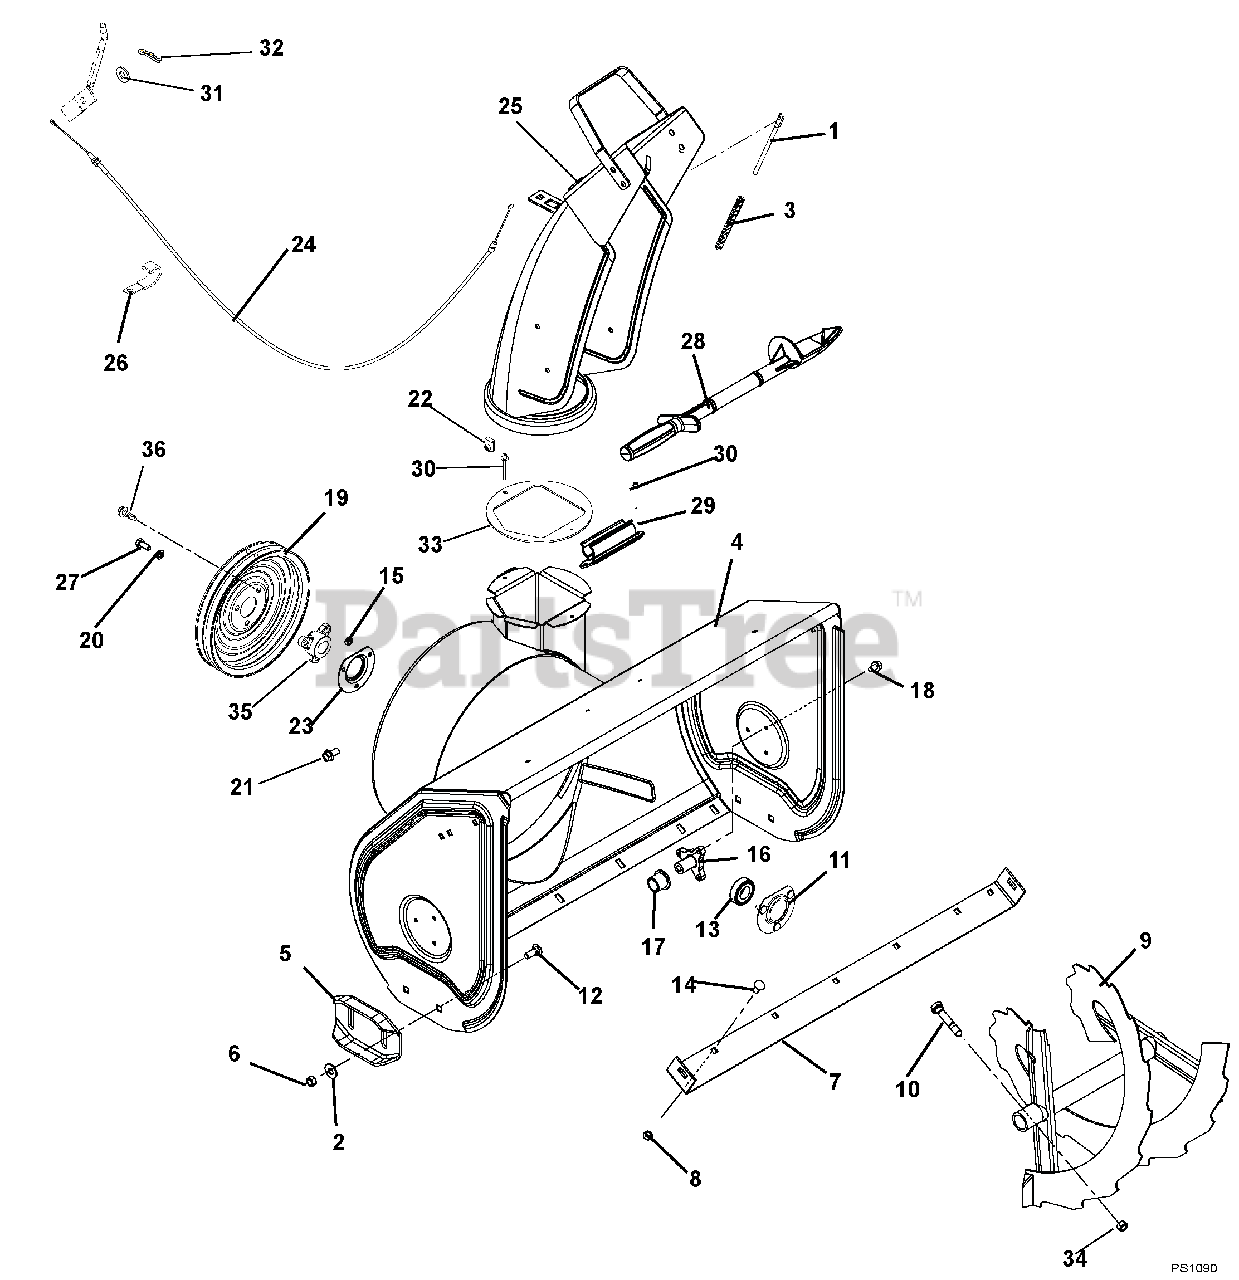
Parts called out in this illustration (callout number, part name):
1	ROD, DEFLECTOR CAP
2	@WSHR-FL-STL.438X1.00X.083 YWZ
3	SG-COMP .08X.40X6.50 14#/IN
4	HOUSING, BLOWER - 24" W/DECAL
4	HOUSING, BLOWER - 27" W/DECAL
4	HOUSING, BLOWER - 30" W/DECAL
5	SKID SHOE, REVERSIBLE - ORANGE
6	@NUT-LK-CTR .38-16 YWZC
7	BLADE, SCRAPER-24"
7	BLADE, SCRAPER-27"
7	BLADE, SCRAPER-30"
8	@NUT-LK-TOP-FLG .31-18 YWZC
9	RAKE, LEFT HAND-24" DELUXE
9	RAKE, RIGHT HAND-24" DELUXE
9	RAKE, LEFT HAND-27" DELUXE
9	RAKE, RIGHT HAND-27" DELUXE
9	RAKE, LEFT HAND-30" DELUXE
9	RAKE, RIGHT HAND-30" DELUXE
10	SHEAR BOLT SERVICE ASSEMBLY
11	BEARING FLANGE
12	@BLT-RDHDSHSQNK.38-16X1.0 G5YZ
13	BRG-BALL .876 X 1.750 X .50
14	@BLT-RHDSSQNK .31-18X.62 G5YZ
15	@NUT-LK-CTR .25-20 YWZC
16	SUPPORT, RAKE BUSHING
17	BSHG-FLG, NY.778 ID X 1.018 OD
18	SCR-TAP .25-20X.50 HWH TR YWZ
19	PULLEY, SPIN FORM DUAL GROOVE
20	WSHR-LK .312X.097 HVY YWZC
21	SCR-TAP.31-18X.50 HWH TR YWZ
22	NUT-RTNR .375-16X.37
23	BEARING FLANGE
24	CABLE, DEFLECTOR
25	CHUTE, DISCHARGE-W/DEFLECTOR
25	CHUTE, DISCHARGE W/CAP & DECAL
26	J-CLAMP
27	BLT-HEX .31-24X.75 YWZC GR5
28	DEVICE, SNOW CLEAN OUT
29	MOUNT, SNOW CLEAN OUT
30	RVT-POP .187 YZ
31	@WSHR-FL-STL.281X.62X.065 YWZC
32	PIN-HAIR INT .06X.18X.77
33	BAFFLE, DISCHARGE NECK
34	@NUT-LK-CTR .31-18 YWZC
35	PULLEY HUB, BOLT-ON D-BORE .87
36	@SCR-TAP .31-18X.50 HWH TR YWZ
